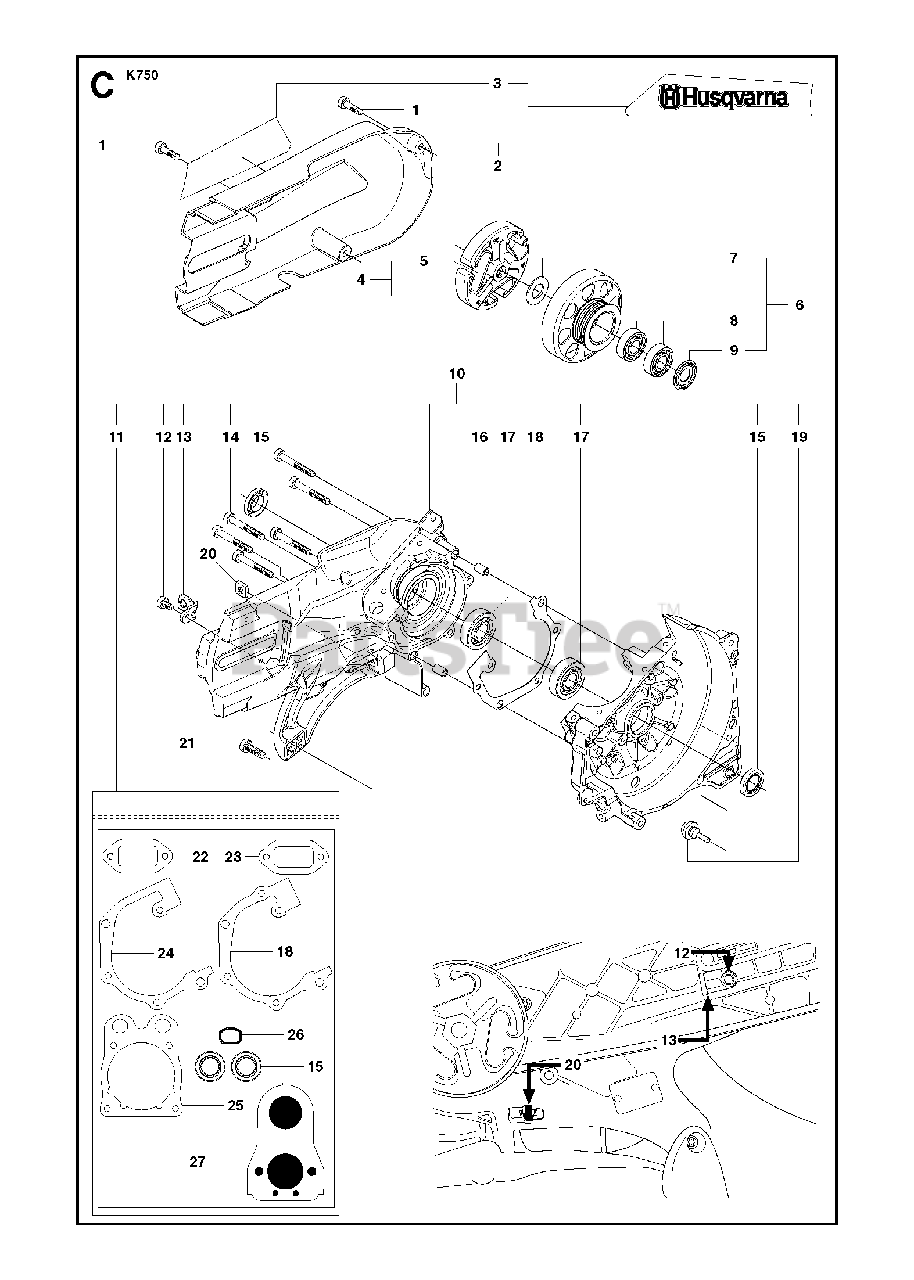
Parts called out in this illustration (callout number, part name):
1	SCREW ITXSCM
2	BELT GUARD ASSYIncl. 3
4	CLUTCH ASSYIncl. 5
5	CLUTCH SPRING
6	DRIVING PULLEY ASSYIncl. 7 - 9
7	WASHER
8	BALL BEARING
10	CRANKCASE ASSYIncl. 11 - 19
11	GASKET KITIncl. 15, 18, 22 - 27
12	SCREW ITXSCM
14	SCREW ITXSCM
15	SEALING RING
16	GUIDE BUSHING
17	BALL BEARING
21	SCREW ITXSCM
23	GASKET
27	GASKET
